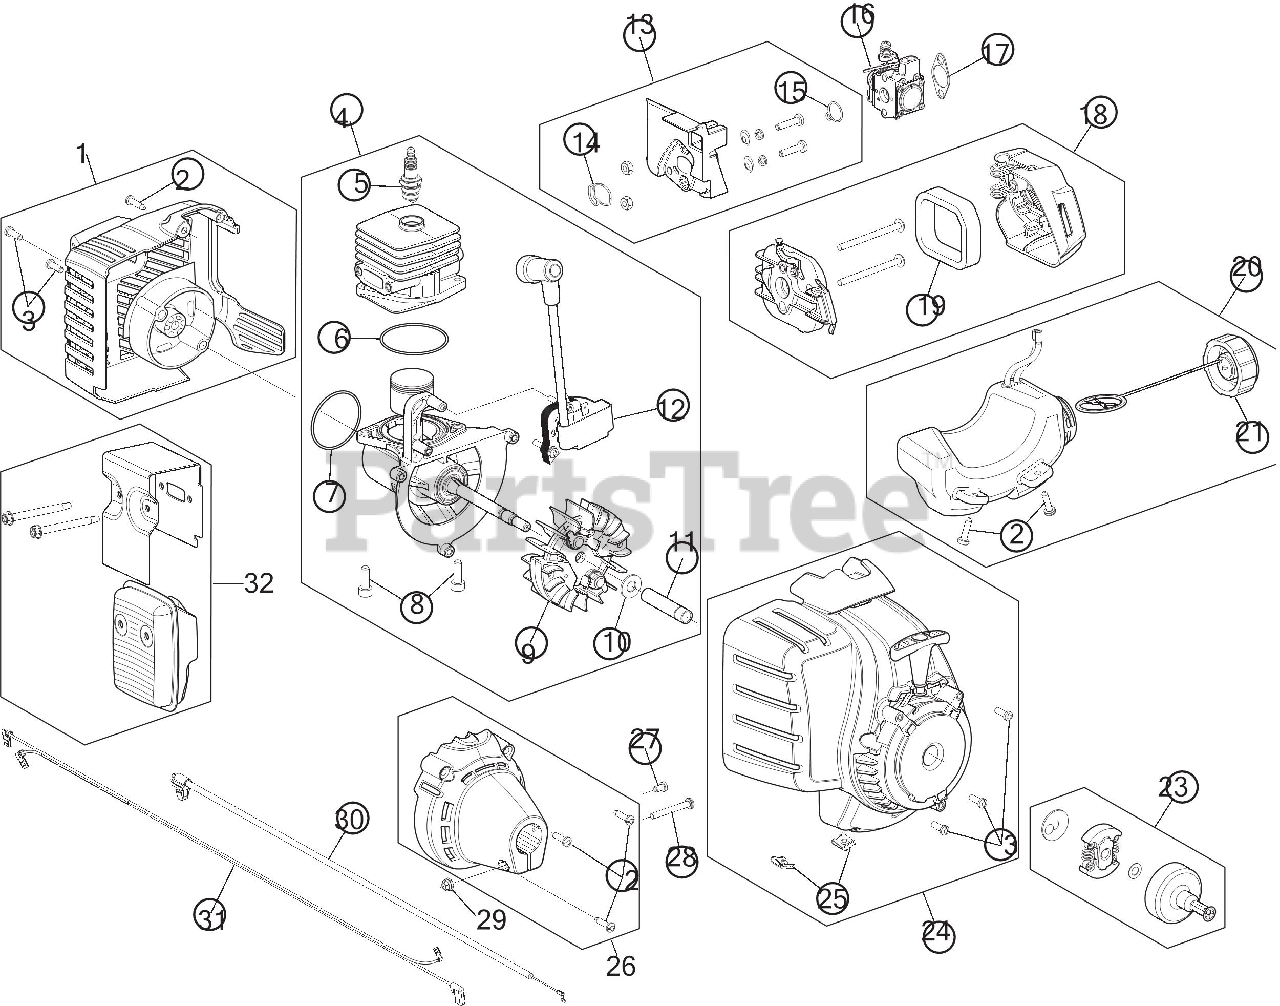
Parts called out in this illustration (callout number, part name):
1	ENGINE COVER RR
2	SCREW, #8-16X.750 PH
3	SCREW:10-32X.562:#8P
4	SHORTBLOCK
5	SPARK PLUG
6	O-RING
7	O-RING
8	SCREW, 1/4-20 x .75
9	FLYWHEEL ASSEMBLY
10	BELL WASHER
11	SPACER
12	MODULE MA-103
13	INTAKE ASSEMBLY
14	O-RING
15	O-RING
16	CARBURETOR
17	GASKET CARB
18	AIR CLEANER ASSEMBLY
19	AIR FLITER
20	FUEL TANK ASSEMBLY
21	FUEL CAP ASSEMBLY
22	SCREW 10-6 x .75
23	SMALL CLUTCH ASSEMBLY W/SMALL DRUM
24	STARTER HOUSING RED
25	NUT, TINNERMAN U-T
26	CLUTCH COVER
27	SCREW, 8-32 x .312 P
28	SCREW
29	HEX NUT
30	THROTTLE CABLE
31	LEAD WIRES
32	MUFFLER ASSEMBLY
